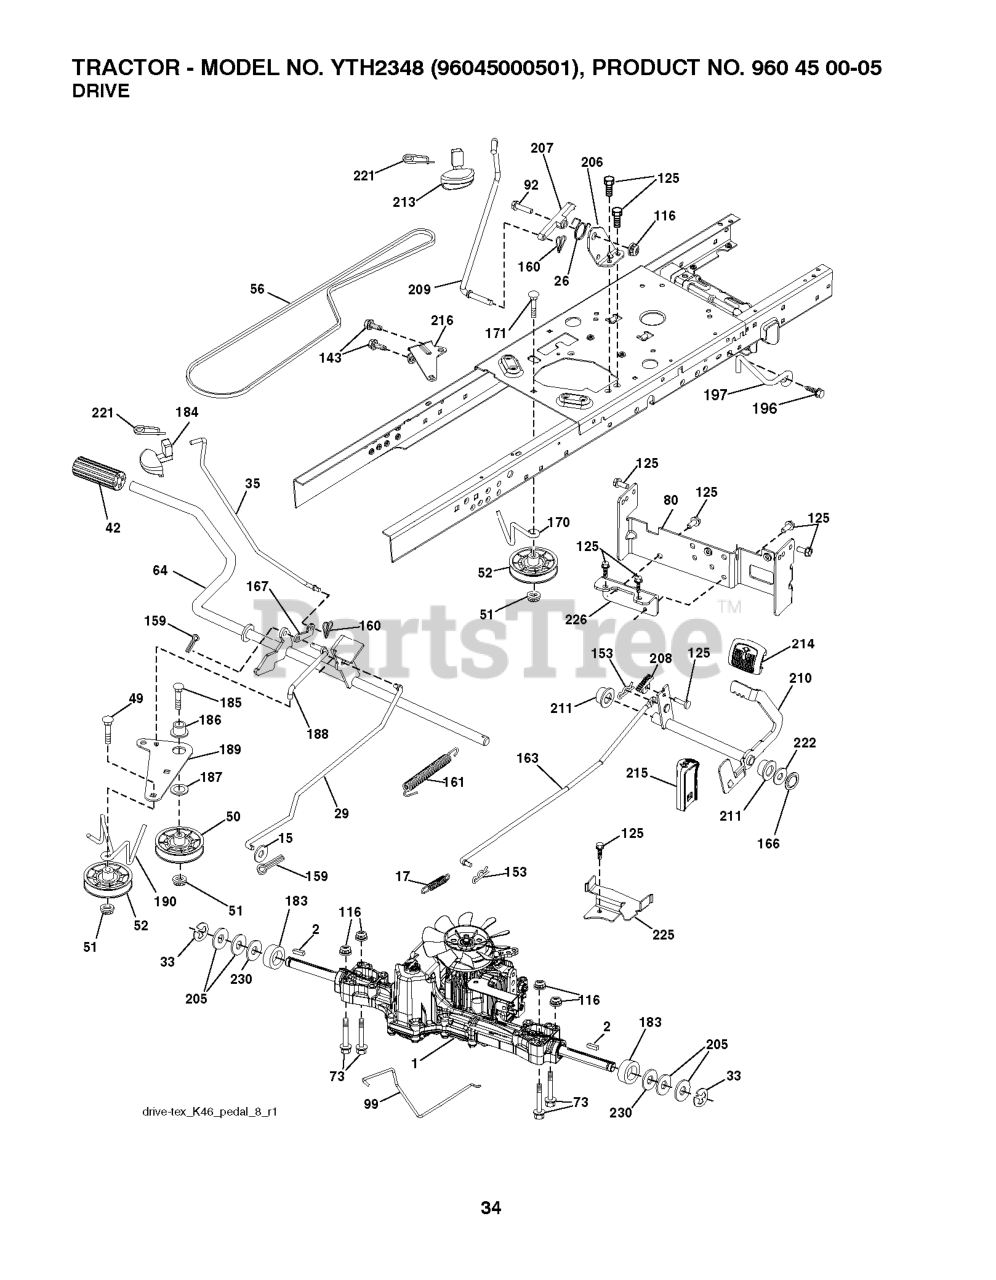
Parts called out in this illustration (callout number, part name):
1	TRANSAXLE, TUFFTORQ K46
2	SQUARE KEY
15	WASHER
17	SPRING.BRAKE.K46.GREEN
26	SPRING.RETURN.CRUISE
29	ROD.BRAKE.K46
35	ROD.BRAKE.PARKING.GT.H
42	PEDAL COVER T
50	IDLER.FLAT.910.OFFSET
51	NUT LOCK FLG 3/8-16 UNC
52	IDLER.V-GROOVE.910.OFFSET
56	V-BELT.MOWER.92.40.42/K46
64	SHAFT.ASM.PEDAL.BRK.CNTR
73	BOLT HEX 5/16-18 GR 5
80	STRAP TORQUE.ASM.K46/18"TEX
92	BOLT
99	ROD.SPRING.BYPASS.K46.LT.Z
116	NUT LOCK HEX FLANGE 5/16-18
125	SCREW
143	Screw 5/16-18 x 1/2 Hex, Self Tapping 5/16-18 x 1/2
153	RETAINER M
159	COTTER PIN
160	RETAINER CLIP
161	SPRING, RETURN LT
163	ROD.CONTROL.PEDAL.K46
166	NUT.PUSH.625.2006
167	LATCH.BRAKE.SPRING
170	KEEPER.V-IDLER.CENTER.
183	SPACER AXLE
184	HANDLE.PARKG.BRK.HUSQ X667
186	SPACER.RETAINER
187	WASHER 12/32X2X10GA
188	RP.LINK.CLUTCH.GROUND.DRIVE
189	BELLCRANK.GROUND.DRIVE.TEX.
190	KEEPER.BELLCRANK.DRIVE
196	SCREW 3/8-16X1
197	LINK.CLUTCH.ANIT-ROTAT
206	BRKT.MOUNT.LATCH.CRUIS
207	LATCH.CONTROL.CRUISE
208	GEAR.SECTOR.CONTROL.CR
209	ROD.CONTROL.CRUISE.GT.
210	ROCKER.ASM.PEDAL.CONTR
211	BEARING.NYLON
213	KNOB.CONTROL.CRUSIE.HU
214	PEDAL.FORWARD.TEX.GT.4
215	PEDAL.REVERSE.TEX.GT.4
216	BRACKET.PULLEY.IDLER.W/TEX
221	RETAINER.SPRING.CLIP.H
222	WASHER 21/32 X 1-1/4 X 10 GA.
225	KEEPER.BELT.TRANSAXLE.K46
226	BRACKET.MOUNT.TORQUE.K46.TLT
230	WASHER.HARDENED
